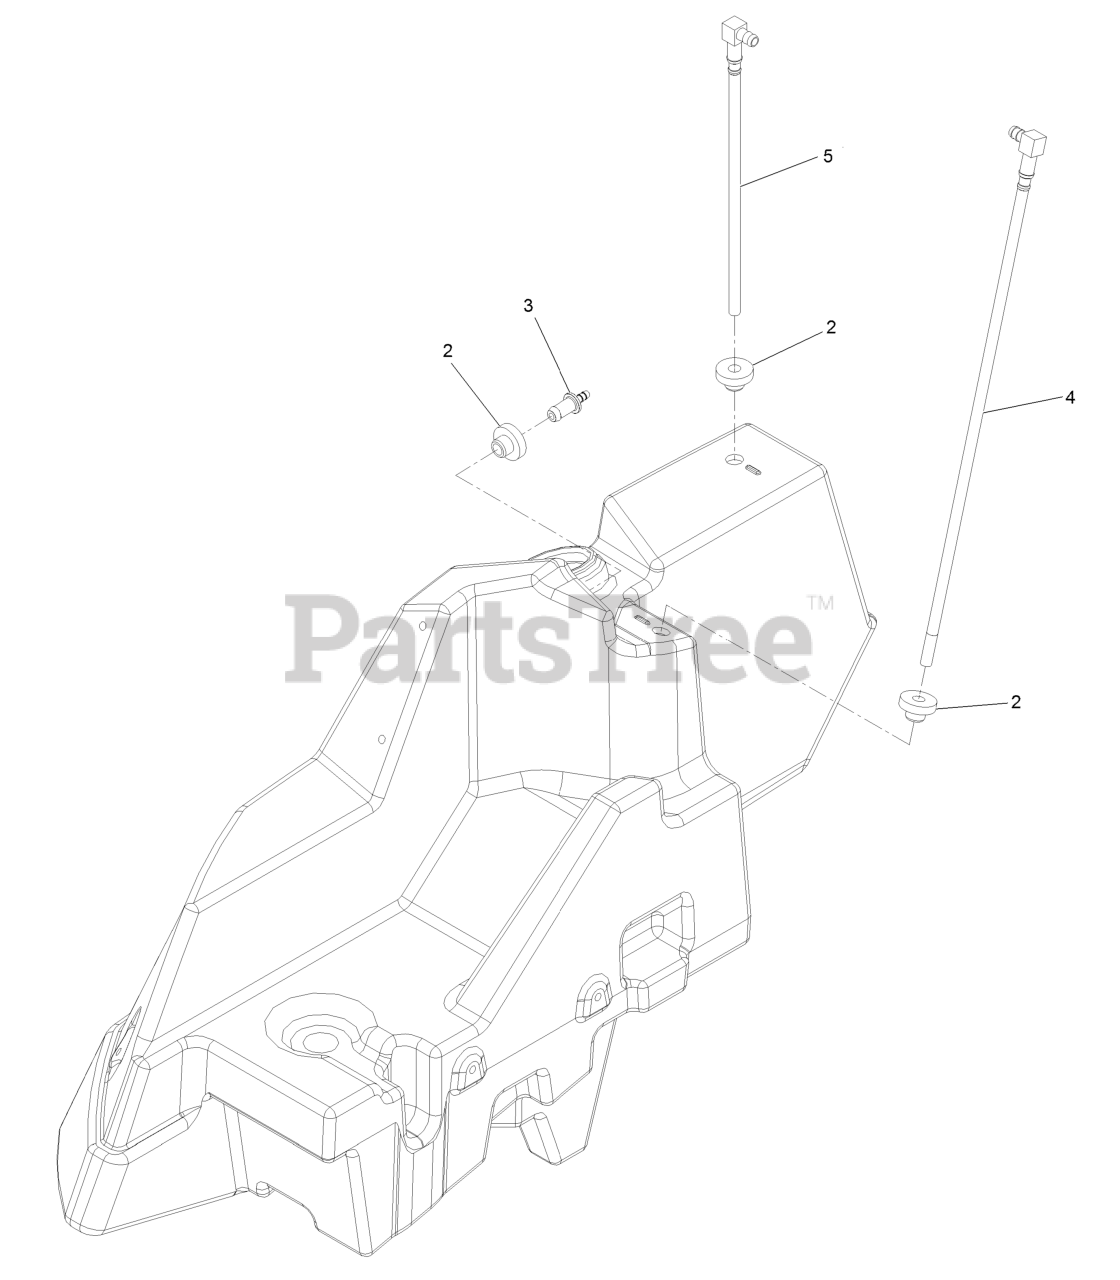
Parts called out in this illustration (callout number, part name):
2	Bushing
3	Fitting-Orifice, Straight
4	Pick-Up-Fuel
5	Return-Fuel
